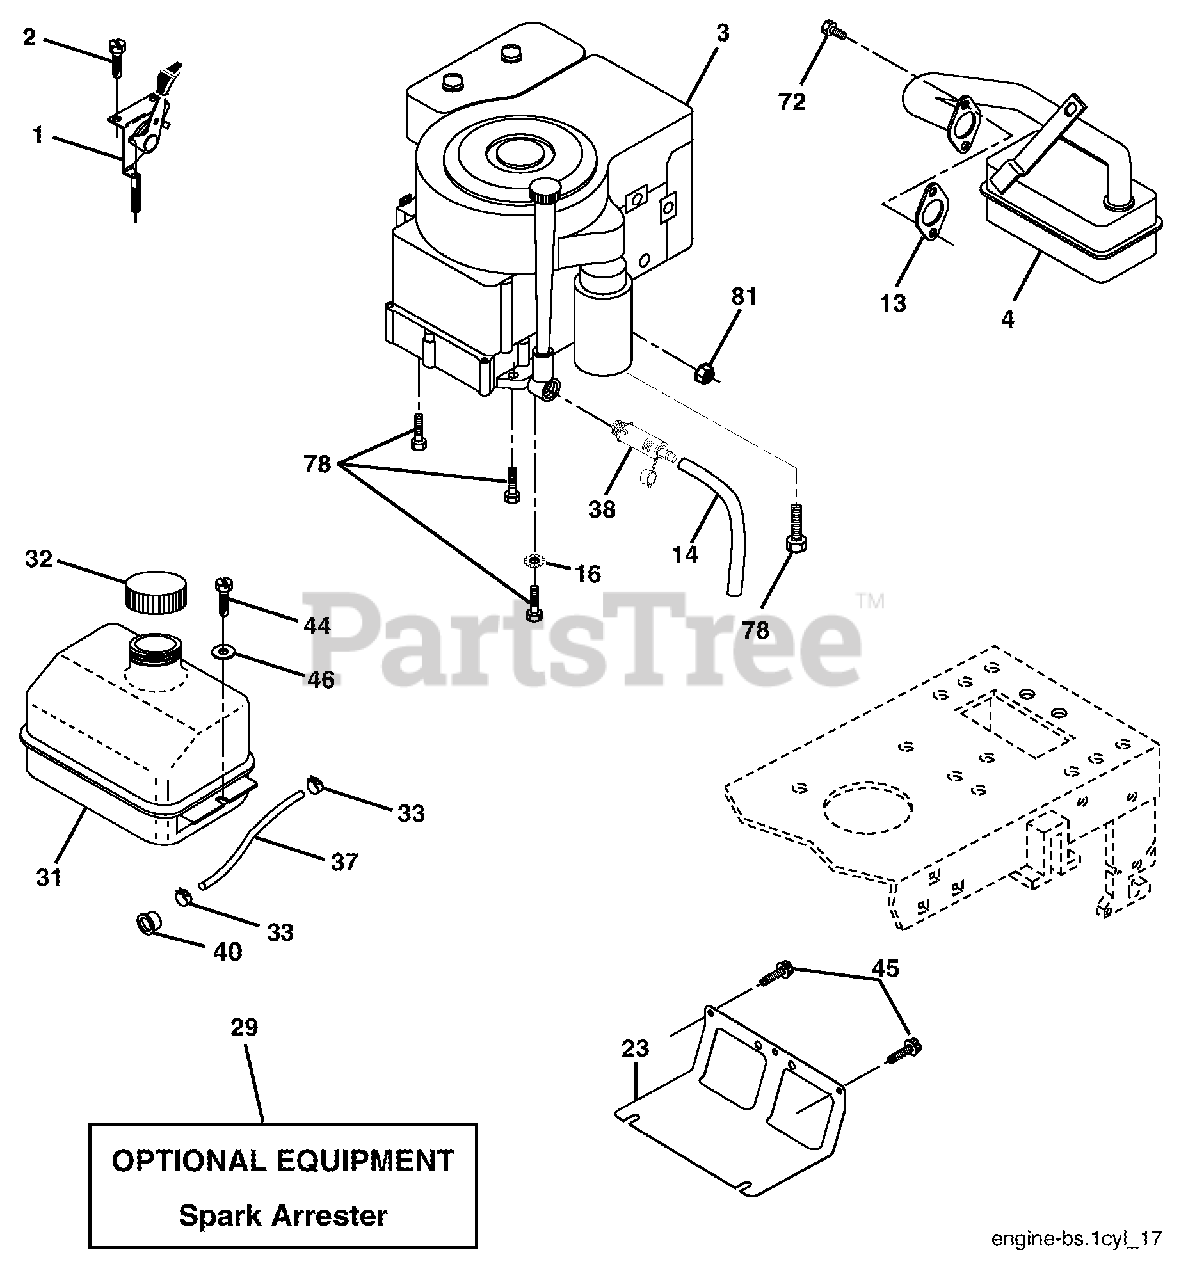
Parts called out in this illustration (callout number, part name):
1	Control Throttle/Choke Flag
2	Screw Hex Thd Cut 1/4-20x1/2
4	Muffler Exhaust B&S Lt
13	Gasket 1 313 Id Tin Plated
14	Tube Drain Oil Easy
16	Washer Lock Ext Tooth 3/8
23	Shield Browning/Debris Guard
29	Arrestor Spark
31	Tank Fuel 1 25 Fr
32	Cap Asm Fuel W/sym Vented
33	Clamp Hose Blk
37	Line Fuel 20"
38	Plug Drain Oil Easy
40	Bushing Snap Nyl Blk Fuel Line
44	Screw Hexwsh Thdrol 1/4-20x3/4
45	Screw Hex Wsh Thdrol 3/8-16
46	Washer 9/32 X 7/8 X 16ga
72	Screw Socket Head 5/16-18 x 1
78	Screw Thdrol 3/8-16x1-1/4
81	Nut Keps Hex 1/4-20 Unc
